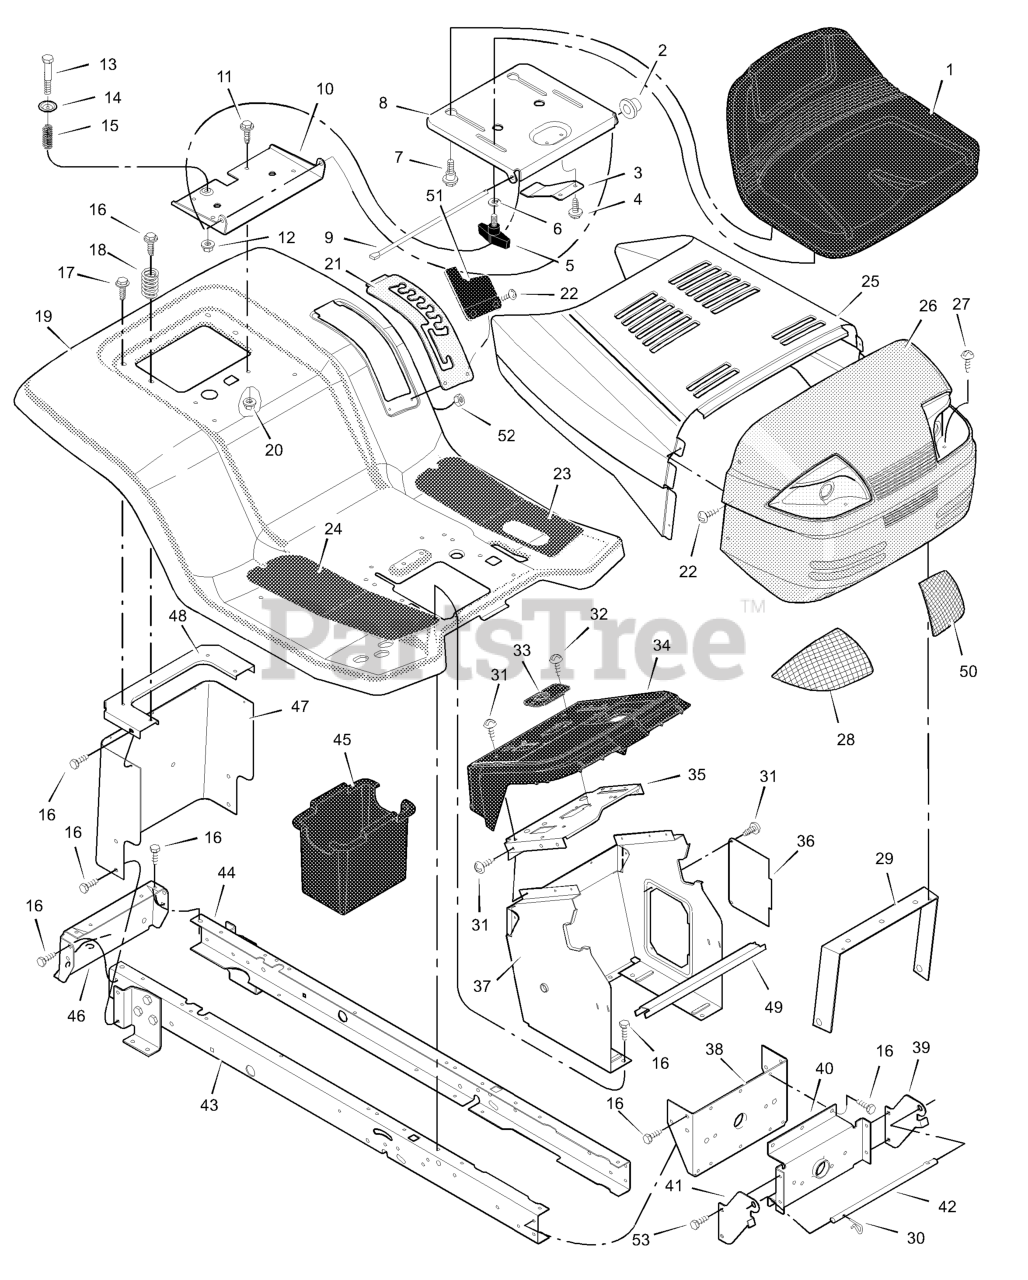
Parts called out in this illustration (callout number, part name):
1	Seat
2	Cap, Push On
5	Bolt, Wing
6	Washer
7	Bolt, Shoulder
8	Support, Seat
9	Rod, Pivot
10	Bracket, Pivot
11	Bolt
13	Bolt, Shoulder
15	Spring
19	Deck, Seat
20	Nut
21	Plate, Index
23	Mat, Left
24	Mat, Right
25	Hood
26	Grille Assembly
28	Lens, Right
29	Brace, Grille
30	Pin, Hair
31	Screw
33	Bearing, Steering
35	Plate, Dash
36	Panel, Access
37	Support, Dash
38	Bracket, Rear Hanger
39	Support, Left Grille
40	Axle, Hanger
41	Support, Right Grille
42	Rod, Pivot
43	Frame, Right
44	Frame, Left
45	Container, Battery
46	Plate, Hitch
47	Plate, Rear
48	Top, Rear Plate
50	Lens, Left
51	Cover, Detent
